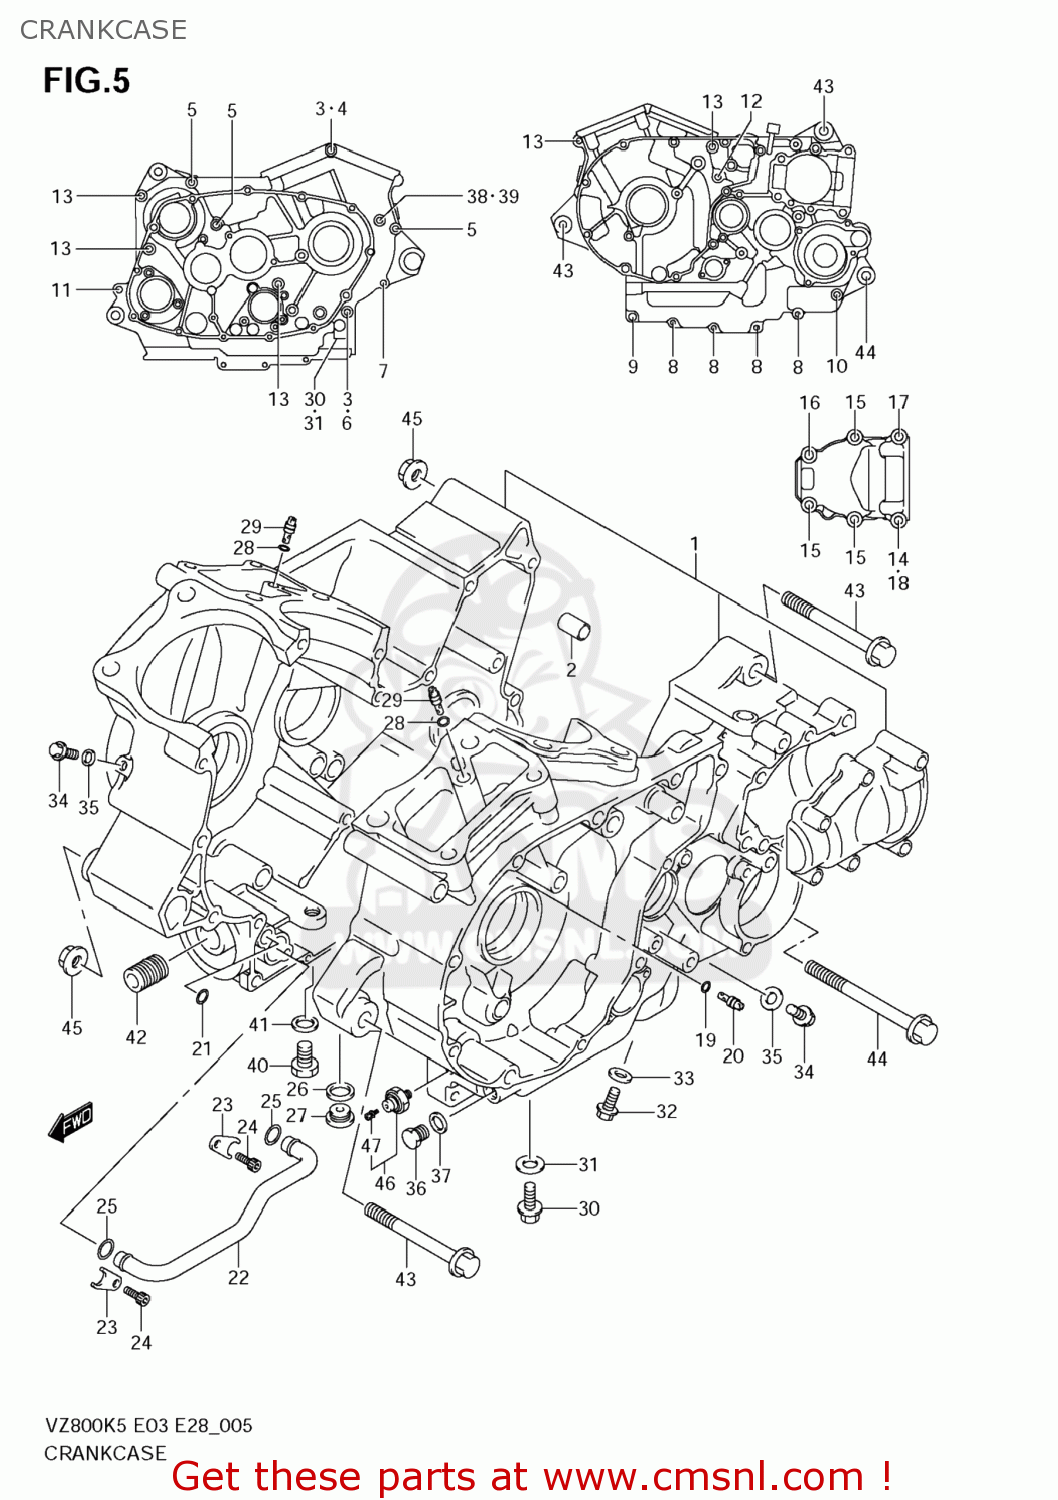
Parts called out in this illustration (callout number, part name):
1	CRANKCASE SET
2	PIN(8.4X11X20)
3	GASKET(8.2X16X1) (NAS)
4	BOLT(8X160)
5	BOLT(8X120)
6	BOLT(8X105)
7	BOLT(8X95)
8	BOLT
9	BOLT
10	BOLT
11	BOLT
12	BOLT
13	BOLT(8X95)
14	GASKET(8.2X16X1) (NAS)
15	BOLT
16	BOLT
17	BOLT
18	BOLT
19	O RING(D:1.2,ID:4)
20	JET,OIL GALLERY
21	O RING(D:1.9,ID:12.6)
22	PIPE,OIL GALLERY
23	CLAMP,OIL PIPE
24	BOLT(6X12)
25	O RING(D:3.1,ID:14.8)
26	GASKET(16X22X2) (NAS)
27	PLUG
28	O RING(D:1.2,ID:4)
29	JET,AIR(14)
30	BOLT
31	GASKET(8.2X14X1) (NAS)
32	PLUG(10X12)
33	GASKET(10X14X3.6) (NAS)
34	BOLT
35	GASKET(5.8X13X1.2) (NAS)
36	PLUG(14X12)
37	GASKET(13.8X18.8X4.8) (NAS)
38	BOLT(8X12)
39	GASKET(8.2X14X1) (NAS)
40	PLUG(12X20)
41	GASKET(12.1X16.2X3.7) (NAS)
42	UNION,OIL STAND
43	BOLT(10X135)
44	BOLT(10X160)
45	NUT
46	SWITCH ASSY,OIL PRESSURE
47	BOLT,OIL PRESSURE SWITCH
